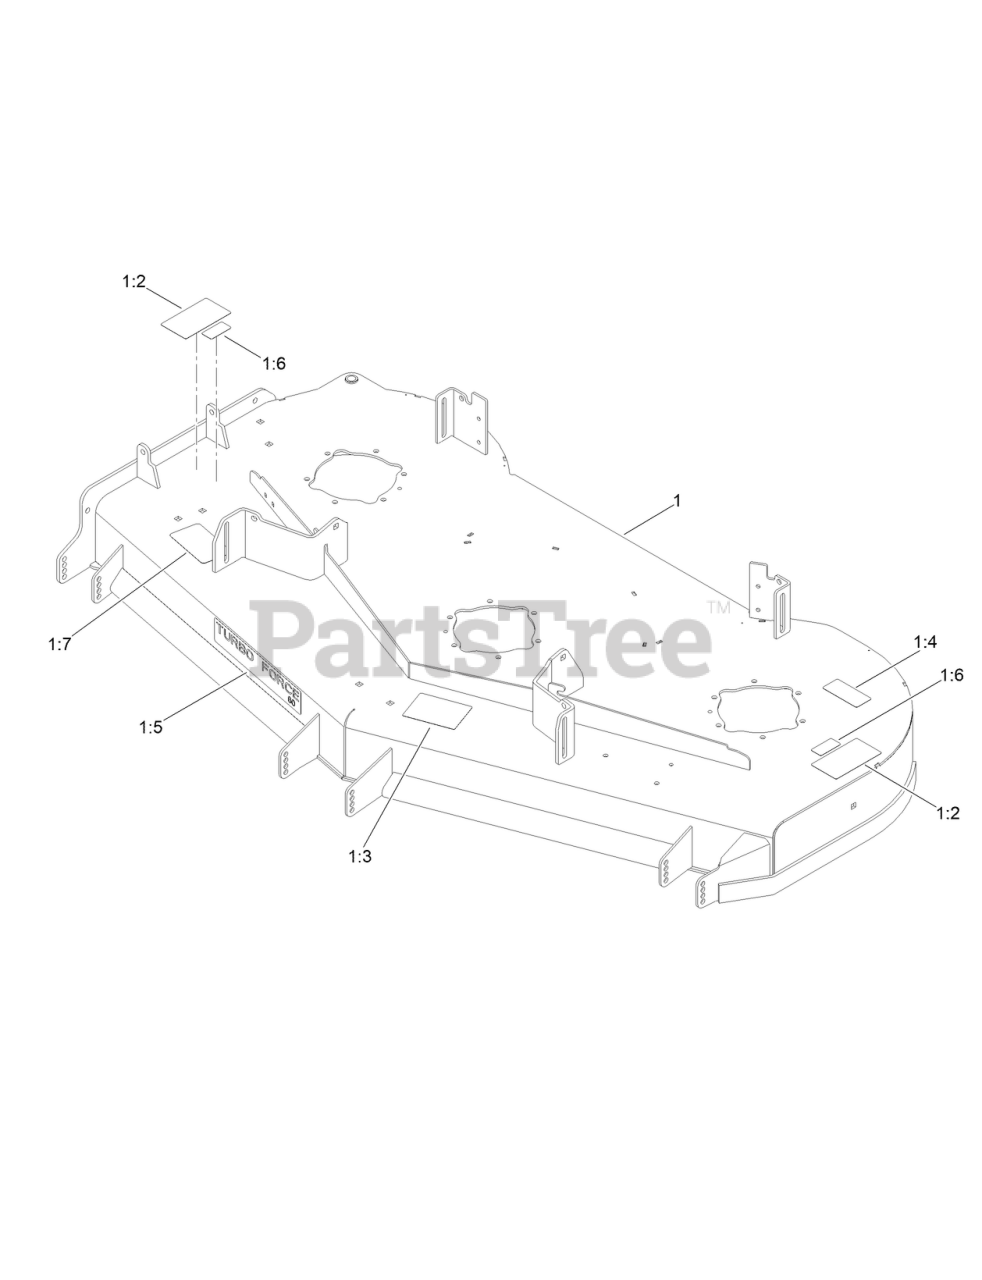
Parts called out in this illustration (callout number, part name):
1:2	DECAL-DANGER
1:3	DECAL-SCALP, ANTI
1:4	DECAL-DANGER
1:6	DECAL-NO SPRAY
1:7	DECAL-ADJUSTABLE BAFFLE
